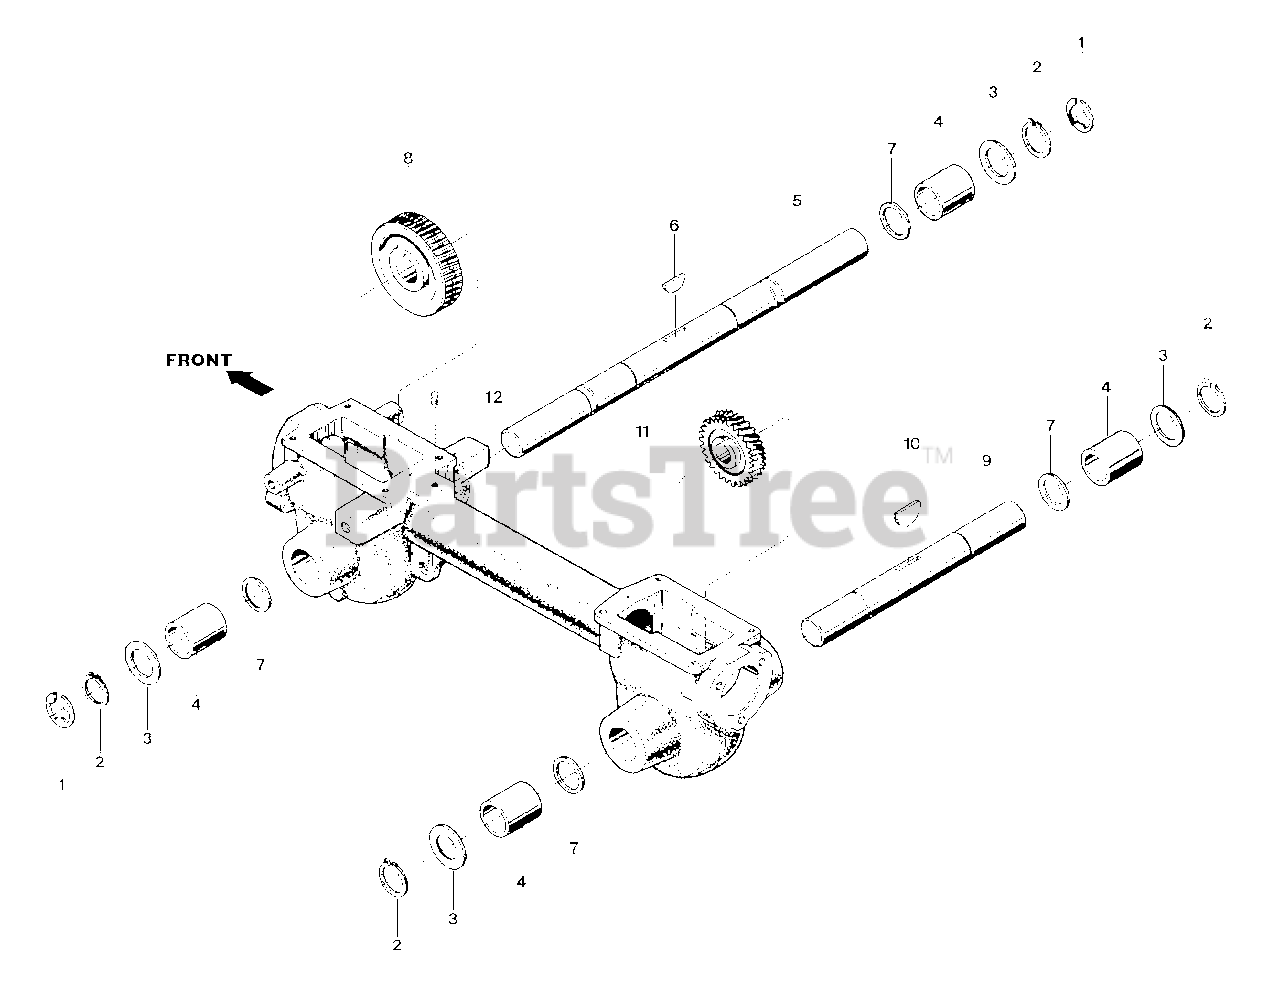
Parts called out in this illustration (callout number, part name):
1	Retainer, Snap Ring,"E"Type
2	Retainer, Snap Ring
3	Shim, 0.062"Thick
4	Bushing, Bronze
5	Wheel Shaft
6	Key, Hi Pro, 1/4 x 1
7	Spacer
8	Worm Gear, Wheel Shaft
9	Tiller Shaft
10	Woodruff Key, Tiller Shaft
11	Worm Gear, Tiller Shaft
